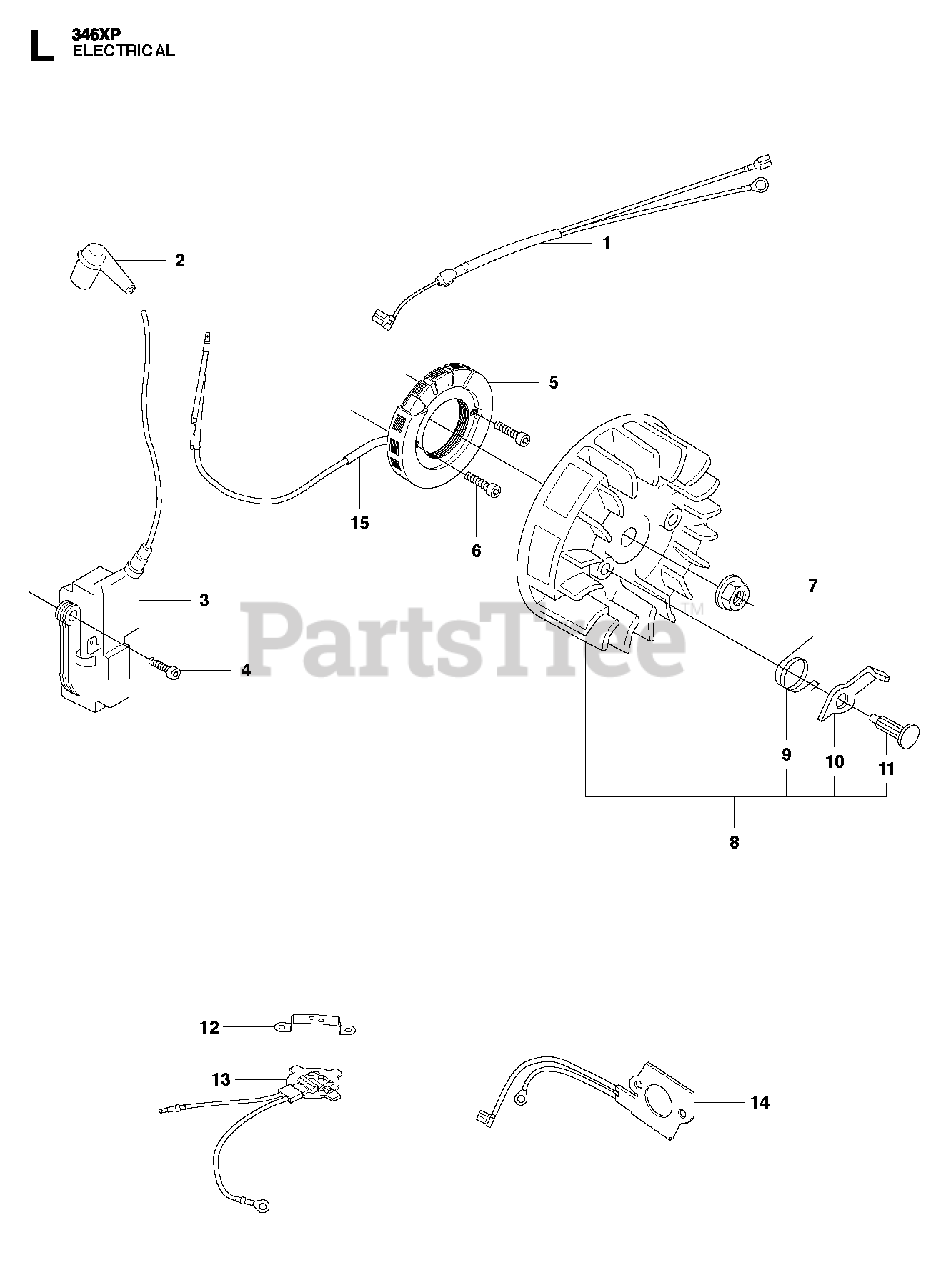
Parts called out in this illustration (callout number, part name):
1	WIRING ASSY
1	WIRING ASSEMBLY
2	SPARK PLUG CONN. KIT
3	IGNITION MODULE
5	GENERATOR
5	GENERATOR STATOR
7	NUT W/ WASHER
8	FLYWHEEL (G)
8	RP FLYWHEEL
9	%SPRING, STARTER CATCH
10	PAWL
11	RIVET
12	RETAINER
13	THERMOSTAT ASSY
14	Heating Plate
15	Cable Cover
